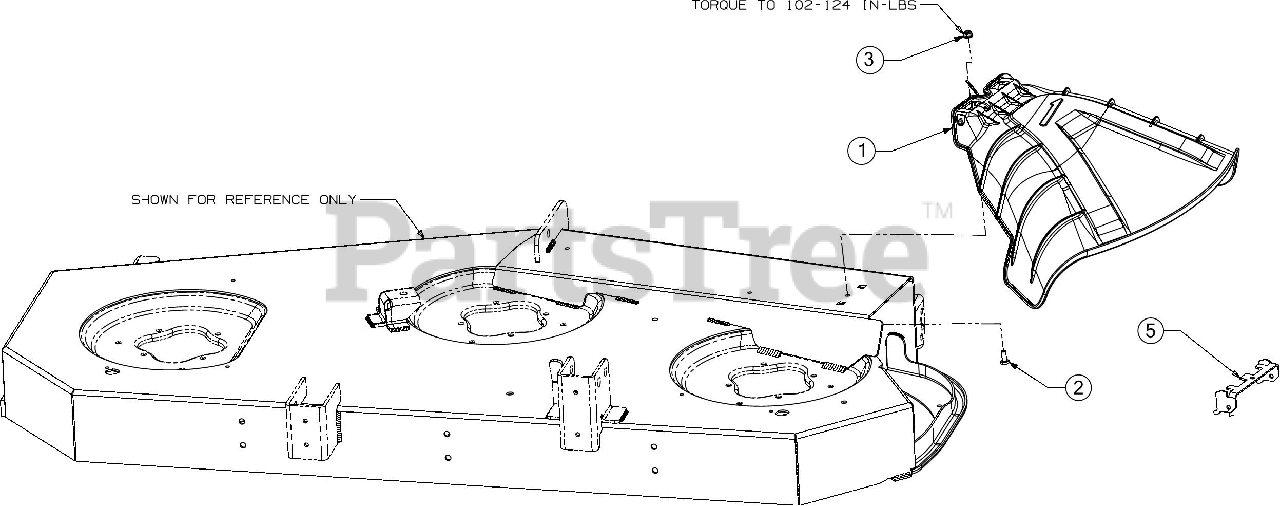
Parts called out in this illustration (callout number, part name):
1	CHUTE ASSEMBLY
1	CHUTE HINGE PIN
1	TORSION SPRING
1	PUSH CAP
2	SCREW 1/4-20 X .620 GR5
3	FLANGE LOCK NUT
5	NOT SERVICEABLE PART
